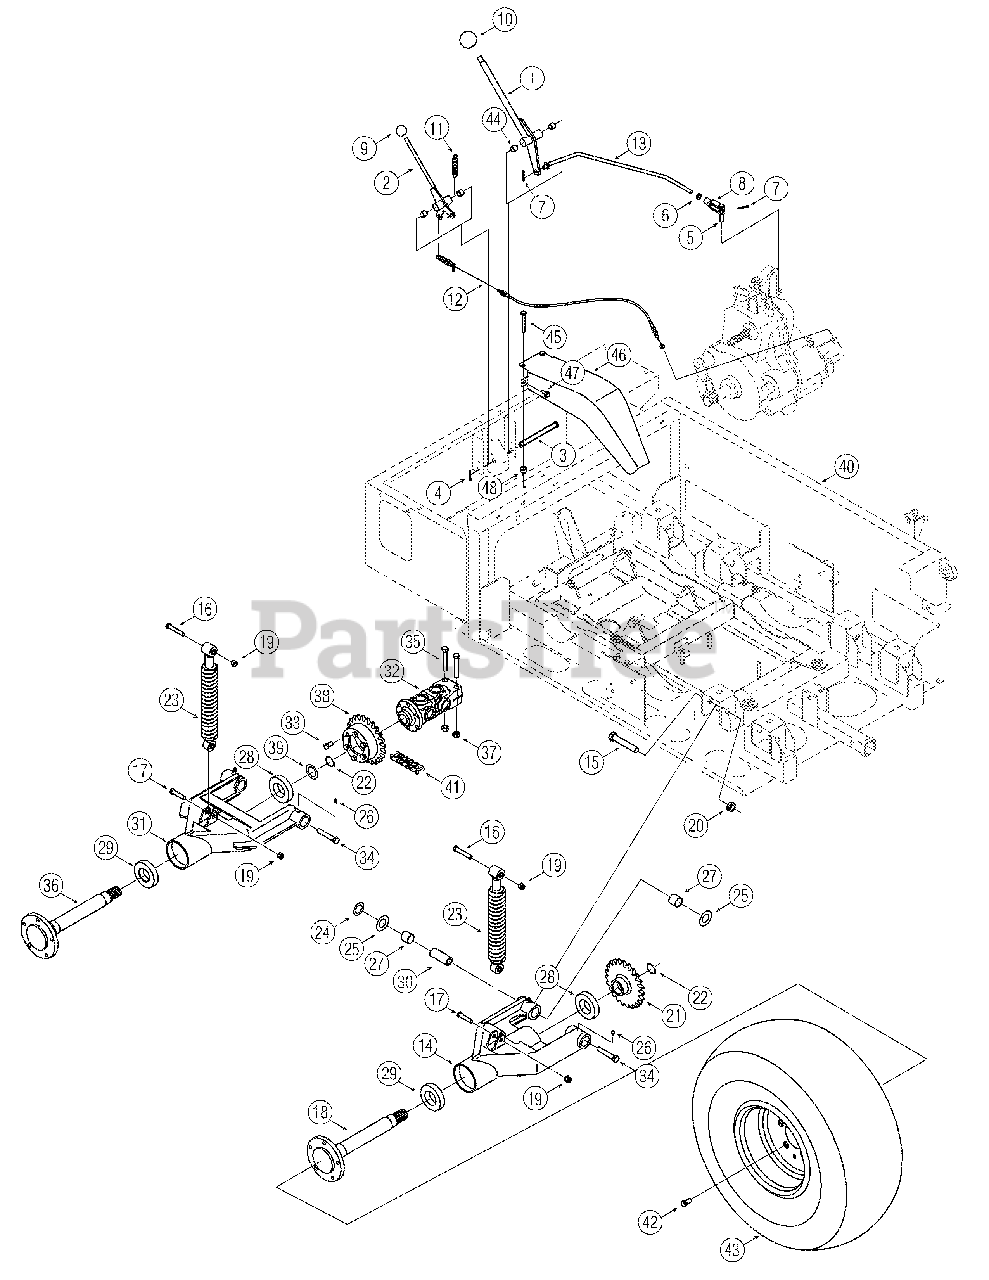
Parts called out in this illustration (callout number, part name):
1	Lever Assembly, Transmission
2	Shifter Assembly, Differential Lock
3	Pin, Clevis,.50 x 5.375
4	Pin, Cotter
5	Pin, Clevis, .375 x 2.0
6	Nut, Jam, 3/8-24
7	Pin, Cotter, .072 x 1.13
8	Clevis, Adjustment
9	Knob, Ball
10	Knob, Ball
11	Spring, Extension, .637 x 2.972
12	Control Cable, Differential Lock
13	Shifter Rod, Transmission
16	Screw, 3/8-16 x 2.25
17	Screw, 3/8-16 x 1.75
18	Axle Shaft, Rear Drive
19	Nut, Hex Lock, 3/8-16
20	Jam Nut, Lock, 5/8-18
22	Retaining Ring, External, 1.14
23	Shock Absorber, 2.9Stroke
24	Washer, Flat, 1.06 x 1.56 x .020
25	Washer, Flat, 1.010 x 1.86 x .060
26	Lube Fitting, 3/16
27	Bearing Flange, 1.0 x 1.125 x 1.0
28	Ball Bearing, Internal Axle
29	Ball Bearing, External Axle
30	Spacer, .63 x 1.0 x 2.594
32	Weld Coupling Assembly
33	Screw, Hex, 3/8-16 x .75, Gr5
34	Screw, Hex, 5/8-18 x 3.5, Gr5
35	Screw, Hex, 7/16-14 x 2.75, Gr5
36	Axle Shaft, Drive Center
37	Nut, Hex Lock,7/16-14
38	Sprocket, Hub, 1.75 - 23T
39	Spacer, 1.78 x 1.88
40	Frame Assembly, Complete
41	Chain, 60-97 Pitch
42	Hex Screw, 7/16-20 x 1.5, Gr5
43	Wheel Ass’y, 25 x 11 x 10, RH, All Terr.
44	Bushing,.504 x.628 x.50
45	Hex Screw, 5/16-18 x 2.50
46	Belt Guard
47	Screw, 5/16-18 x.625
48	Hex Lock Nut, 5/16-18
